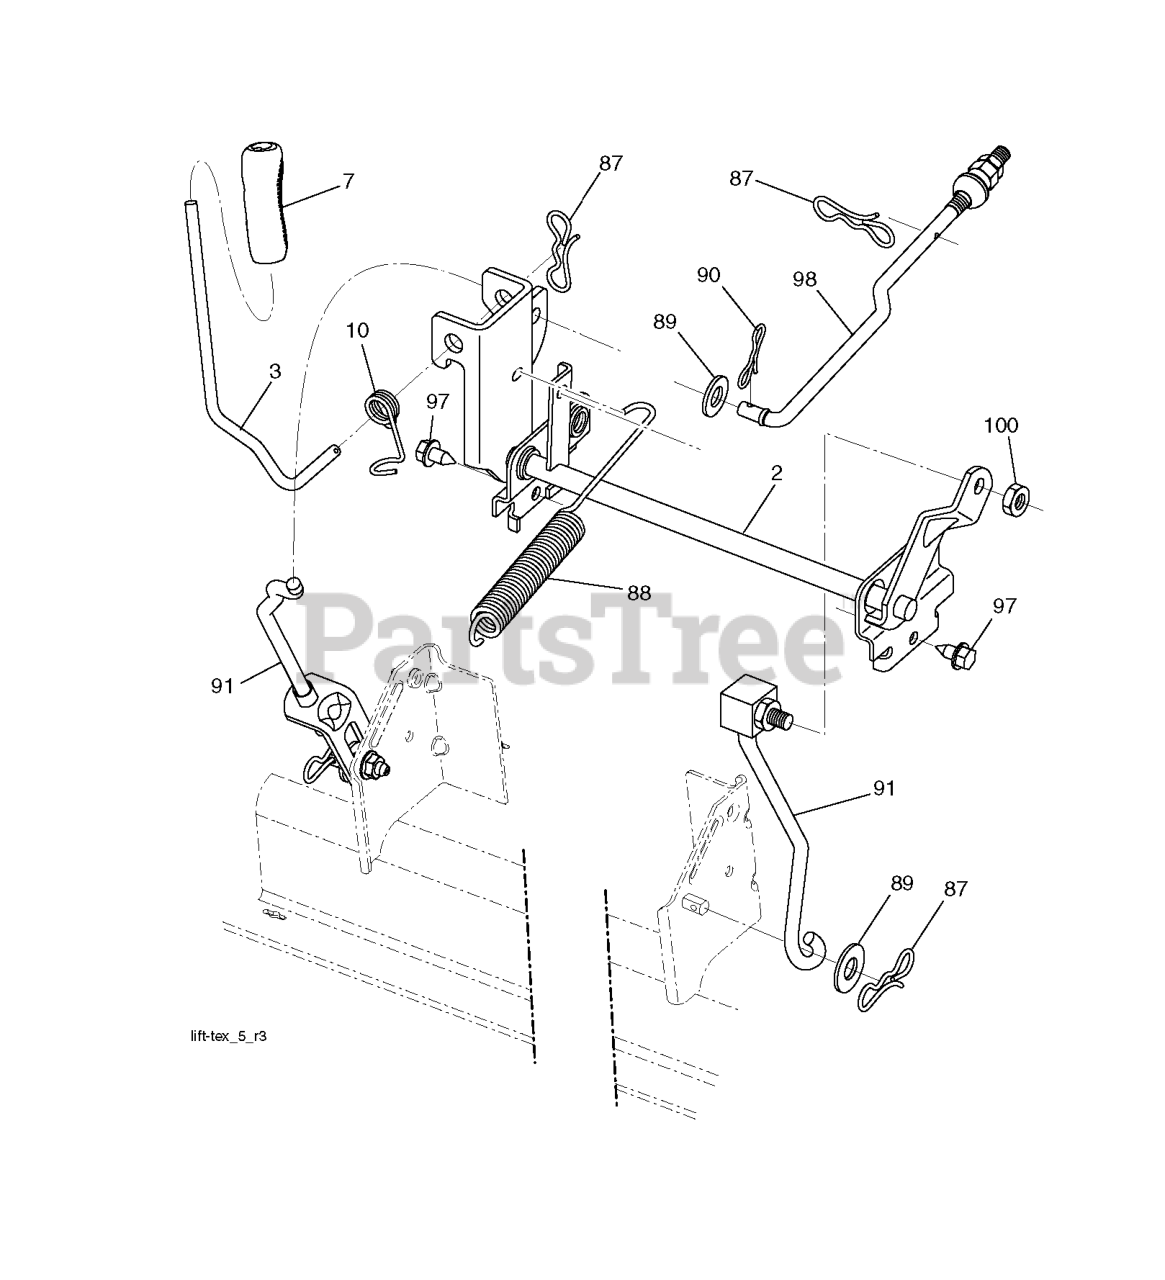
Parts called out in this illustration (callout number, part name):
2	SHAFT.ASM.LIFT.CROSS.H
3	LEVER.LIFT.HANDLE.LT
7	GRIP.HANDLE.LIFT.PVC.BLACK
10	SPRING.TORSION.LIFT.HANDLE
87	PIN.COTTER.7/16.BOW TI.
88	SPRING.LIFT.ASSIST
89	WASHER.CLEAR.ZINC
90	PIN.COTTER.5/16.BOW TI
91	LINK.ASM.LIFT.REAR
97	SCREW 3/8-16X3/4
98	LINK.ASM.SUSP.FRONT.MW
100	LOCKNUT
